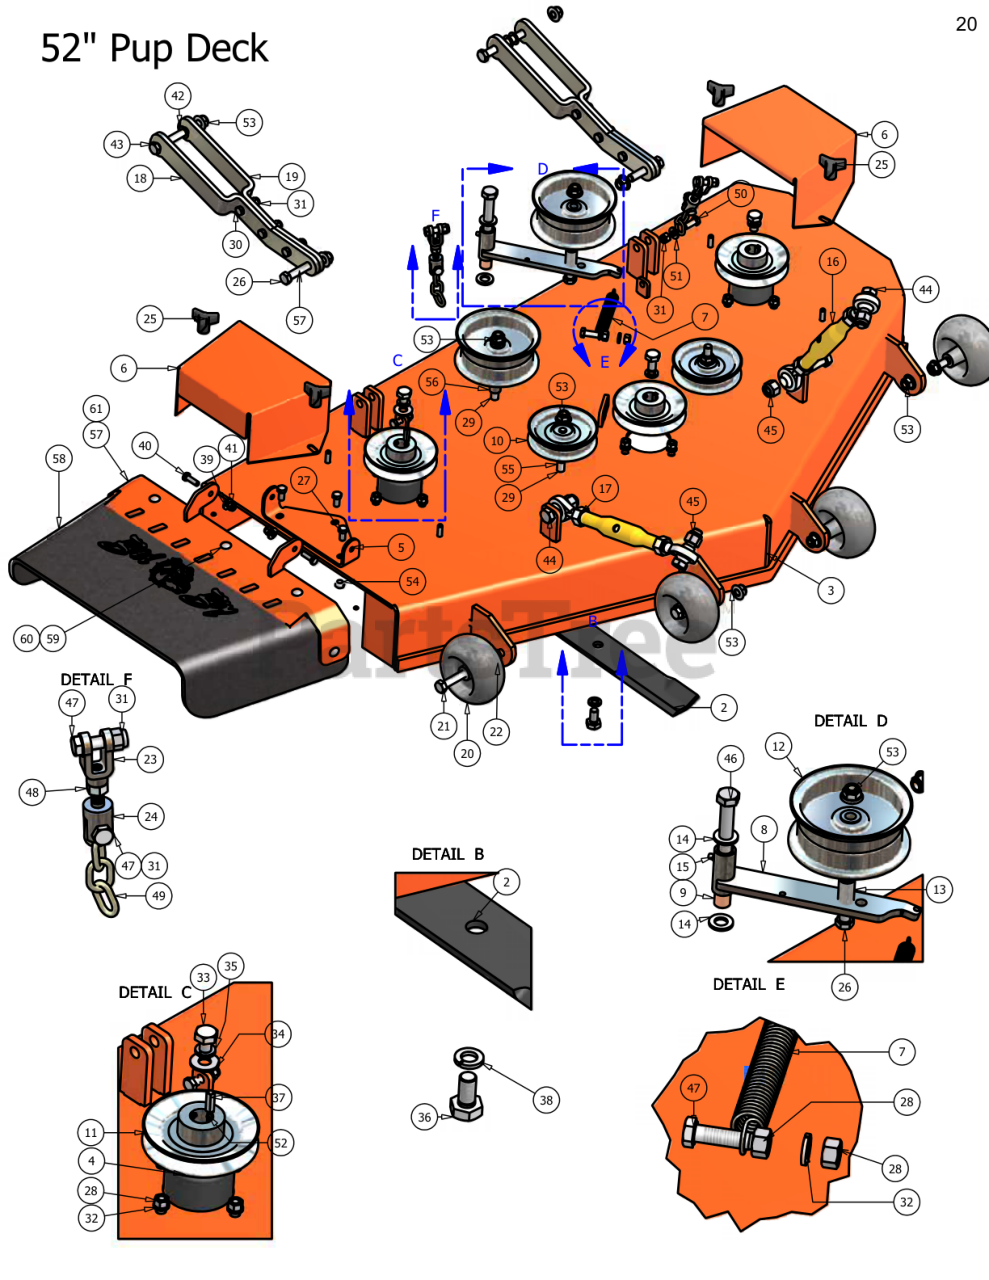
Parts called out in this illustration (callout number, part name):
1	52" Pup Deck Belt
2	52" Fusion Blade
5	Discharge Chute Hanger
6	Pulley Guard
7	Deck Idler Spring
8	Deck Idler Arm
9	5/8" ID x 1 1/8" Brass Bushing
10	4 3/4" Idler Pulley
11	5" Deck Pulley
12	5 3/4" Flat Idler Pulley
13	1 1/4" Pulley Spacer
14	.635 ID Plastic Washer
15	Grease Fitting (Drive-In Type)
16	Turnbuckle
17	3/4" Left Handed Nut
18	Deck Support Arm (left)
19	Deck Support Arm (Right)
20	Anti-Scalp Rollers
21	1/2" x 4" Bolt (Grade 8)
22	1/2" Flange Nut
23	Female Yoke
25	5/16" Knob
26	1/2" x 2 1/2" Hex Bolt
27	3/8" x 3/4" Hex Bolt
28	3/8" Hex Nut
29	1/2" x 3 1/2" Bolt
30	3/8" x 1 1/4" Hex Bolt
31	3/8" Nylock Nut
32	3/8" Lock Washer
33	1/2" x 1 1/2" Bolt
34	1/2" Spring Cupped Washer
35	1/2" Lock Washer
36	5/8" x 1.5" Fine Threaded Bolt
37	1/4" x 1" Key
38	5/8" Lock Washer
39	.360 ID Plastic Washer
40	5/16" x 1" Hex Bolt
41	5/16" Nylock Nut
42	1/2" Brass Washer
43	1/2" x 4 1/2" Bolt
44	5/8" x 2 1/2" Hex Bolt
45	5/8" Nylock Nut
46	5/8" x 4" Hex Bolt
47	3/8" x 1 1/4" Hex Bolt
48	3/8" Fine Threaded Jam Nut
50	3/8" x 1" Hex Bolt
51	3/8" Flat Washer
52	3/8" Set Screw
53	1/2" Flange Lock Nut
54	3/8" Flange Nut
55	1 1/2" Pulley Spacer
56	1 3/4" Pulley Spacer
57	2007 Hanger Plate
58	Rubber Side Discharge
59	5/16" x 1 1/2" Carriage Bolt
60	5/16" Nylock Flange Nut
61	2007 Lower Hanger Plate
